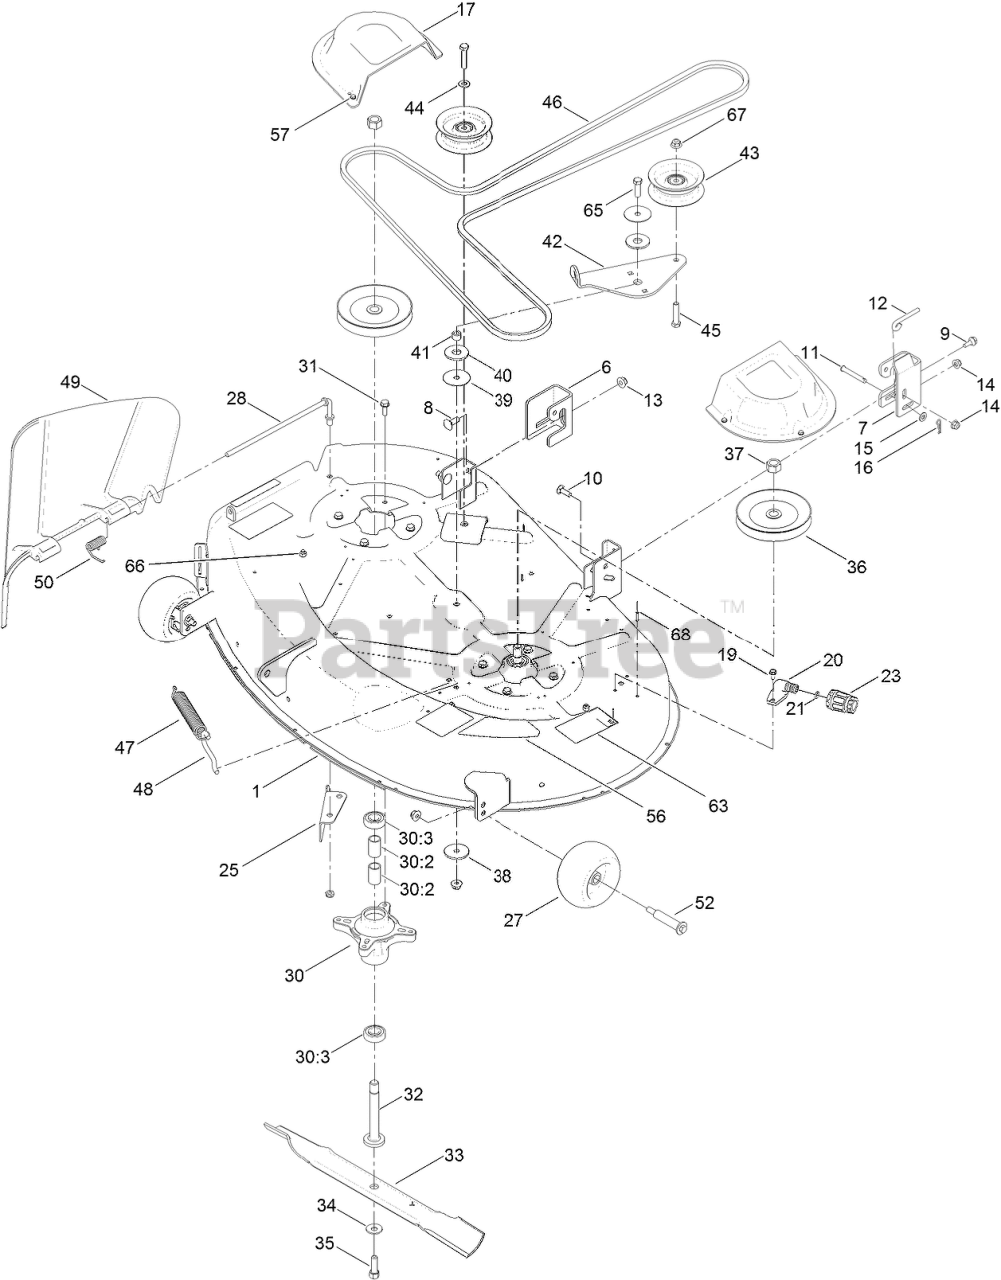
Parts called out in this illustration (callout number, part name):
1	42 INCH DECK AND DECAL ASM
6	BRACKET-HANGER, RH
7	BRACKET-HANGER, LH
8	BOLT-CARR
9	SCREW-SHOULDER, HHF
10	SCREW-CARR
11	PIN-CLEVIS
12	ROD-LEVEL, DECK
13	NUT-HF, NI
14	NUT-HF, NI
15	WASHER-PLAIN
16	PIN-COTTER
17	COVER-BELT
19	SCREW-HWH
20	FITTING-WASHOUT
21	O-RING
23	CONNECTOR-HOSE
25	BAFFLE-CUTOFF
27	ROLLER-SCALP, ANTI
28	ROD-PIVOT
30	SPINDLE ASM
30:2	SPACER
30:3	BEARING-BALL
31	SCREW-TAPTITE
32	SHAFT-SPINDLE
33	BLADE-HIGH LIFT
34	WASHER-BELLEVILLE
35	SCREW-HH
36	Pulley
37	NUT-HEX
38	WASHER-REBOUND
39	WASHER
40	WASHER-FRICTION, COMPOSITE
41	SPACER
42	ARM-IDLER
43	PULLEY-IDLER, FLAT
44	WASHER-FLAT
45	SCREW-HH
46	V-BELT
47	SPRING-EXTENSION
48	HOOK-RETURN, SPRING
49	DEFLECTOR
50	SPRING-TORSION
52	BOLT-SHOULDER
57	SCREW-TAPTITE
63	NUT-LOCK, NI
65	SCREW-HH
66	SCREW-HH
67	NUT-LOCK, NI
68	RIVET-BLIND
